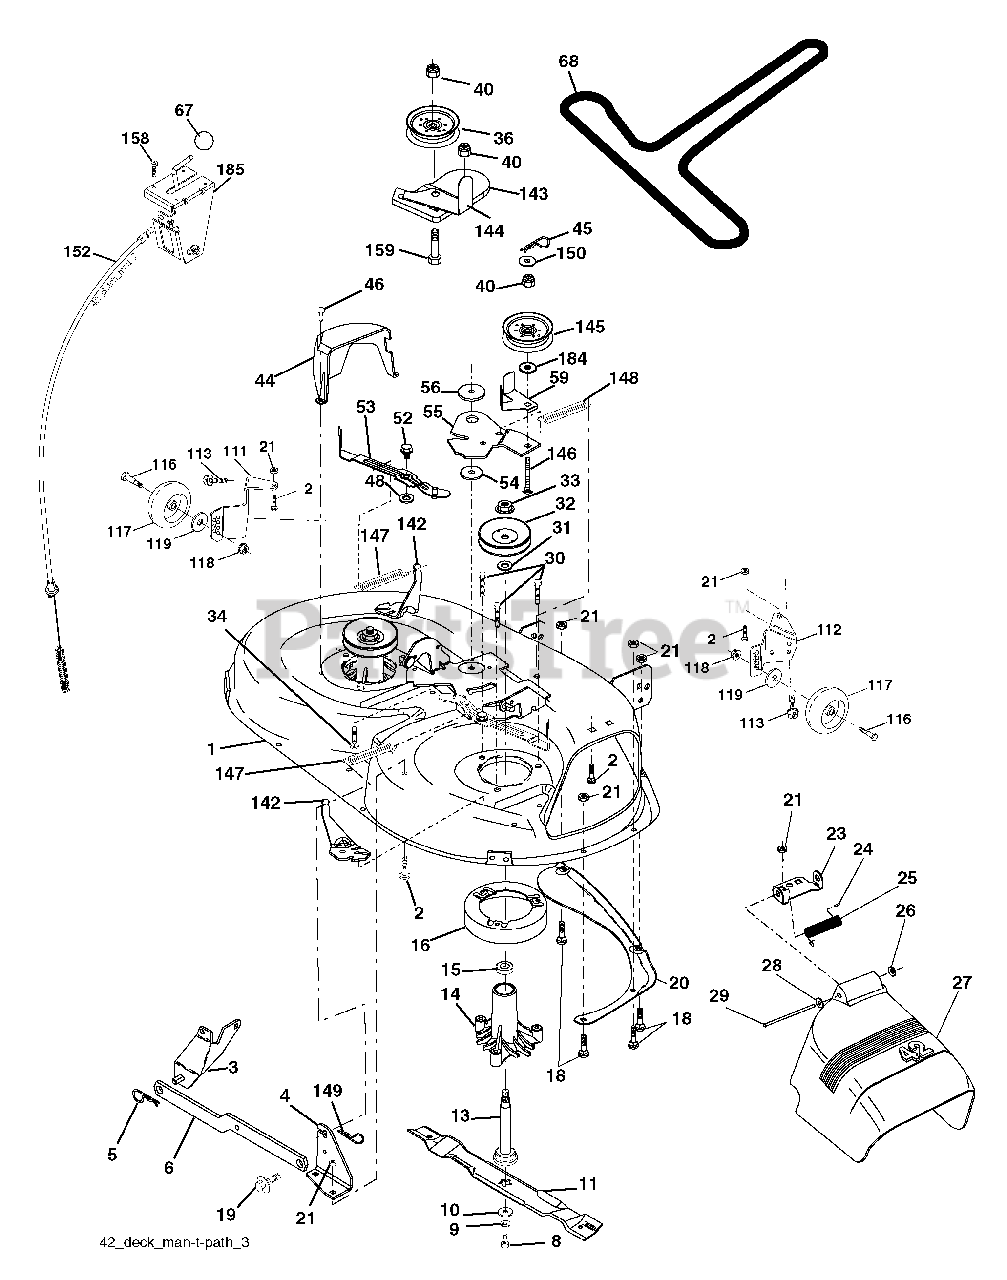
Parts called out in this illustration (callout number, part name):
1	Mower Deck Assembly, 42"
2	Bolt
3	Bracket Asm Fr. Sway Bar 3/42
4	Bracket Asm Deck 42" Sway Bar
5	Retainer Spring
6	Bar Sway Deck
8	Bolt 3/8-24 x 25 Gr. 8 patched
9	Washer, Lock
10	Washer, Hardened (The following blades are available)
11	Blade, 42" Mulching Std (For mulching mowers only)
11	Blade, 42" Mulching Premium (For better wear when mulching)
11	Blade, 42" Hi-Lift (For bagging or discharging)
13	Shaft As sem bly, Mandrel, Vented
14	Housing, Mandrel, Vented
15	Bearing, Ball, Mandrel
16	Stripper, Mandrel Deck
18	Bolt, Carriage 5/16-18 x 5/8
19	Bolt, Shoulder
20	Baffle, Vortex
21	Nut
23	Bracket, Deflector Mower 42"
24	Cap, Sleeve 80 x 112 Blk Mower
25	Spring, Torsion, Deflector 2 52
26	Nut, Push Phos & Oil
27	Shield, Deflector 42" Blk
28	Washer 11/32 x 5/8 x 16 Ga.
29	Rod, Hinge 42" 6 75 W/G
30	Screw Thdrol Washer Head
31	Washer, Spacer Mower Vented
32	Pulley, Mandrel
33	Nut, Toplock 9/16 Flange
34	Bolt
36	Pulley, Idler, Flat
44	Guard, Mandrel, LH
45	Retainer
46	Screw, Thdrol 1/4-20 x 5/8 T
48	Washer, Hardened
52	Bolt, Shoulder 5/16-18 unc
53	Arm Assembly, Pad, Brake
54	Washer, Hardened
55	Arm, Idler
56	Spacer, Retainer
59	Guard TUV Idler
67	Knob
68	V-Belt, 42" Mower
111	Bracket Wheel Gauge LH
112	Bracket Wheel Gauge RH
113	Bolt 5/6-18 hex WSH HD
116	Bolt Shoulder
117	Wheel Gauge
118	Nut Cernter lock 3/8-16 UNC
119	Washer 3/8-7/8 x 14 Ga.
142	Arm Spring Brake Mower
143	Bracket Arm Idler 42"
144	Keeper Belt 42" Clutch Cable
145	Pulley Idler Flat
146	Bolt Carriage Idler
147	Spring Extension
148	Spring Return Idler
149	Retainer Spring Yellow
150	Washer 9/32 x 3/4 x 10 Ga.
152	Clutch Cable 42"
158	Screw Hex Thd Cut 1/4-20 x 1/2
159	Bolt Rdhd Sqn 3/8-16 unc x 1-3/4
184	Washer 13/32 x 7/8 x 10 Ga.
185	Head Asm Cable Clutch
185	Mandrel Assembly
185	Replacement Mower, Complete
